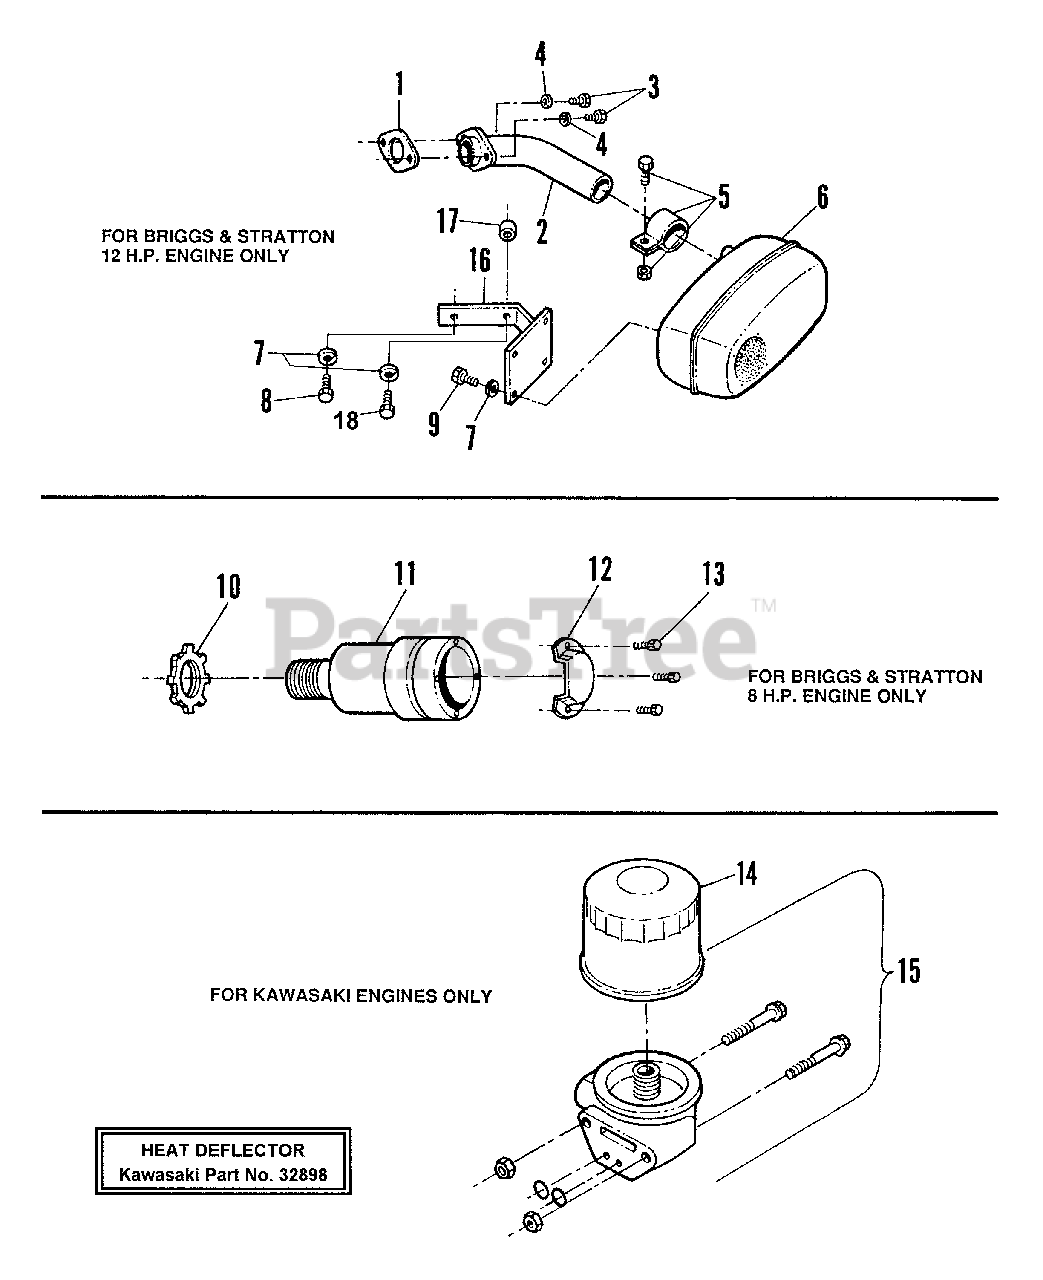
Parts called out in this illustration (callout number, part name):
1	GASKET, Exhaust
2	TUBE, Exhaust Assembly
3	SCREW, 5/16-18 x 3/4" Hex Head Cap, Grade 5
4	WASHER, 5/16" Split Lock
5	CLAMP, Muffler w/Bolt & Nut
6	MUFFLER, Super Lo-Tone (12 HP Briggs)
7	WASHER, 1/4" Split Lock
8	SCREW, 1/4-20 x 3/4" Hex Head Cap, Grade 5
9	SCREW, 1/4-20 x 5/8" Hex Head Cap, Grade 5
10	RING, Locking
11	MUFFLER, Round Lo-Tone (8 HP Briggs)
12	DEFLECTOR, Side Out
13	SCREW, Muffler Deflector
14	FILTER, Oil (12.5 HP Kawasaki)
15	KIT, Oil Filter (12.5 HP Kawasaki)
16	BRACKET, Muffler Mount (12 HP Briggs)
17	SPACER, Muffler Bracket
18	SCREW, 1/4-20 x 1" Hex Head Cap, Grade 5
